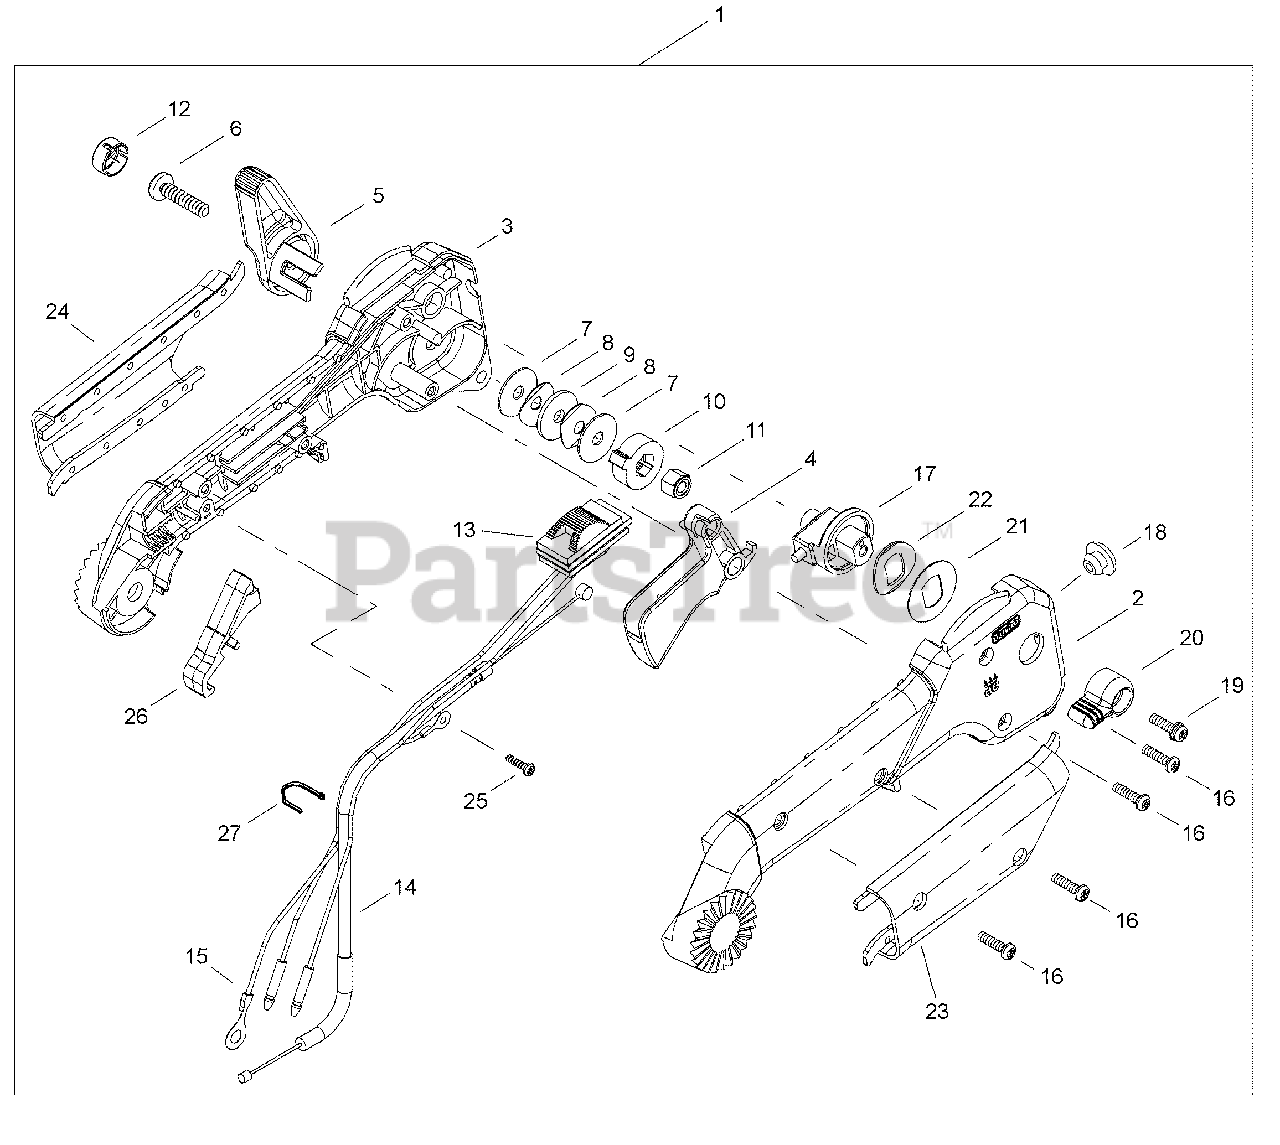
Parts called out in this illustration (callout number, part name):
1	HANDLE ASSY
2	HANDLE, CONTROL - RIGHT
3	HANDLE, CONTROL - LEFT
4	TRIGGER, THROTTLE
5	LEVER, LOCK
6	ADJUSTABLE BOLT
7	WASHER - 6
8	LOCKWASHER
9	WASHER - 6
10	PLATE
11	NUT - 6 -- NYLON
12	CRUISE CONTROL BOLT CAP
13	SWITCH, IGNITION
14	CABLE, THROTTLE
15	LEAD - GROUND
16	SCREW
17	ADJUSTER ASSY
18	PLUG
19	SCREW, METERING LEVER PIN
20	SCREW, METERING LEVER PIN
21	WASHER
22	WASHER - SPRING
23	GRIP - RIGHT
24	GRIP - LEFT
25	SCREW - 3
26	COVER, HANDLE
27	TIE, CABLE
